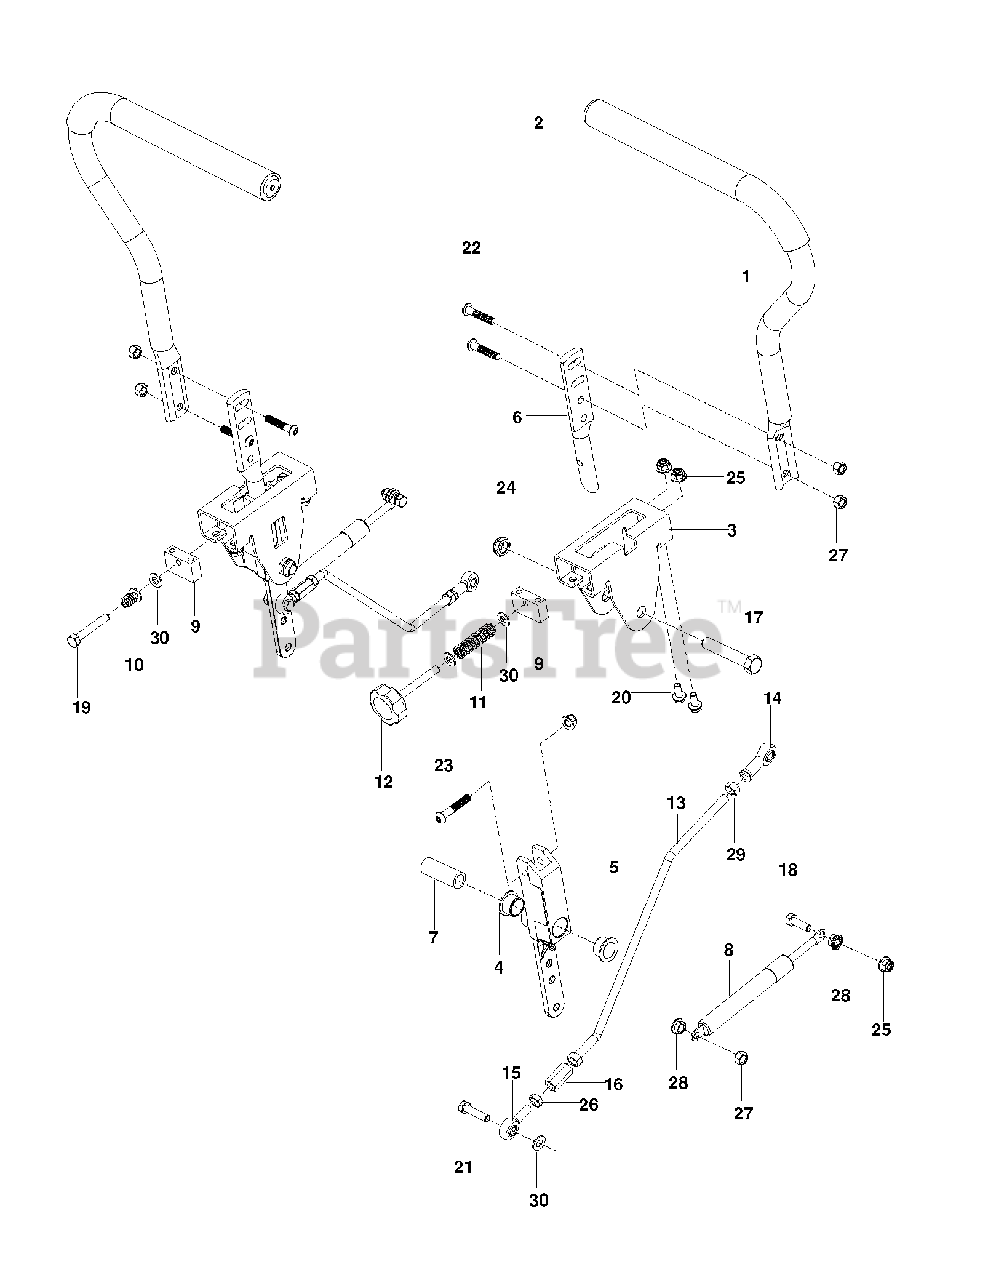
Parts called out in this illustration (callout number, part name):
1	LEVER.STEERING.ASM.(W/GRIP)
2	GRIP, DRIVE LEVER
3	BRACKET, CONTROL
4	BEARING, FLANGE
5	LEVER CONTROL PIVOT
6	LEVER.HANDLE MOUNT
7	SPACER, PIVOT CONTROL
9	BLOCK.TRACKING
11	SPRING COMPRESSION 2.0
12	KNOB
13	ROD MOTION CONTROL
14	RH ROD END
15	RB ROD.END.LH
16	ROD END COUPLER
17	HCS 1/2-13 X 2-3/4 GD 5 ZD
18	BOLT.FIN.HEX.5/16-18UNC X 1.00
19	HEX BOLT
20	HHFS 5/16-18 X 3/4
22	SCREW BUTTONHEAD 5/16-18X1-1/2
23	SCREW 5/16-18 X 1 3/4 BTN-HD
24	NUT 1/2-13 HEX JM NYL
25	5/16-18 NYLOC FLANGE NUT
26	NUT 5/16F LEFTHAND
27	NUT.71038.31-18.HEX.NYLOCK
28	NUT 5/16C WHIZ
30	FLAT WASHER 5/16 SAE
